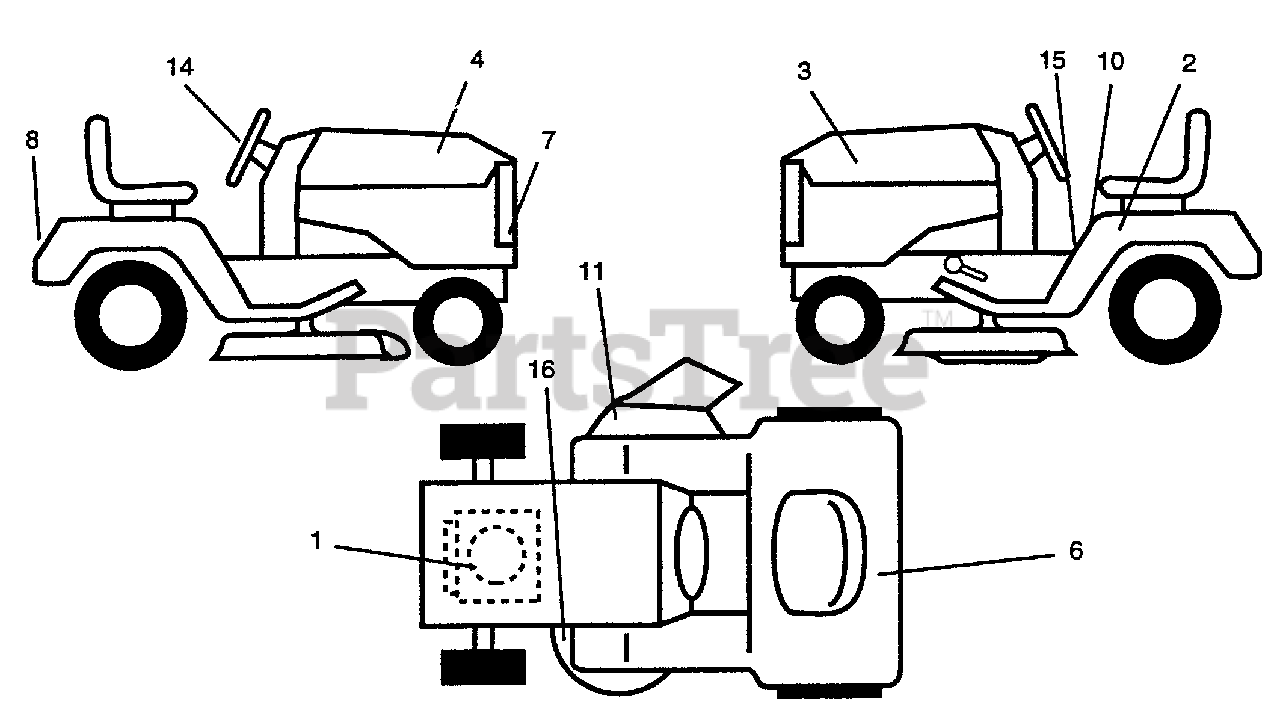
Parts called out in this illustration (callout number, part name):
1	Decal, Engine, HP
2	Decal, Indicator
3	Decal, Hood, L.H.
4	Decal, Hood, R.H.
6	Decal, Caution Battery
7	Decal, Lightbox
8	Decal, Logo, Fender
10	Decal, Fender, Caution
11	Decal, Warning, Multi-Language
14	Decal, Insert Steering
15	Decal, Instruction, Operating
16	Decal, V-Belt Schematic
CR38	Grass Catcher
MK380	Mulch Kit
